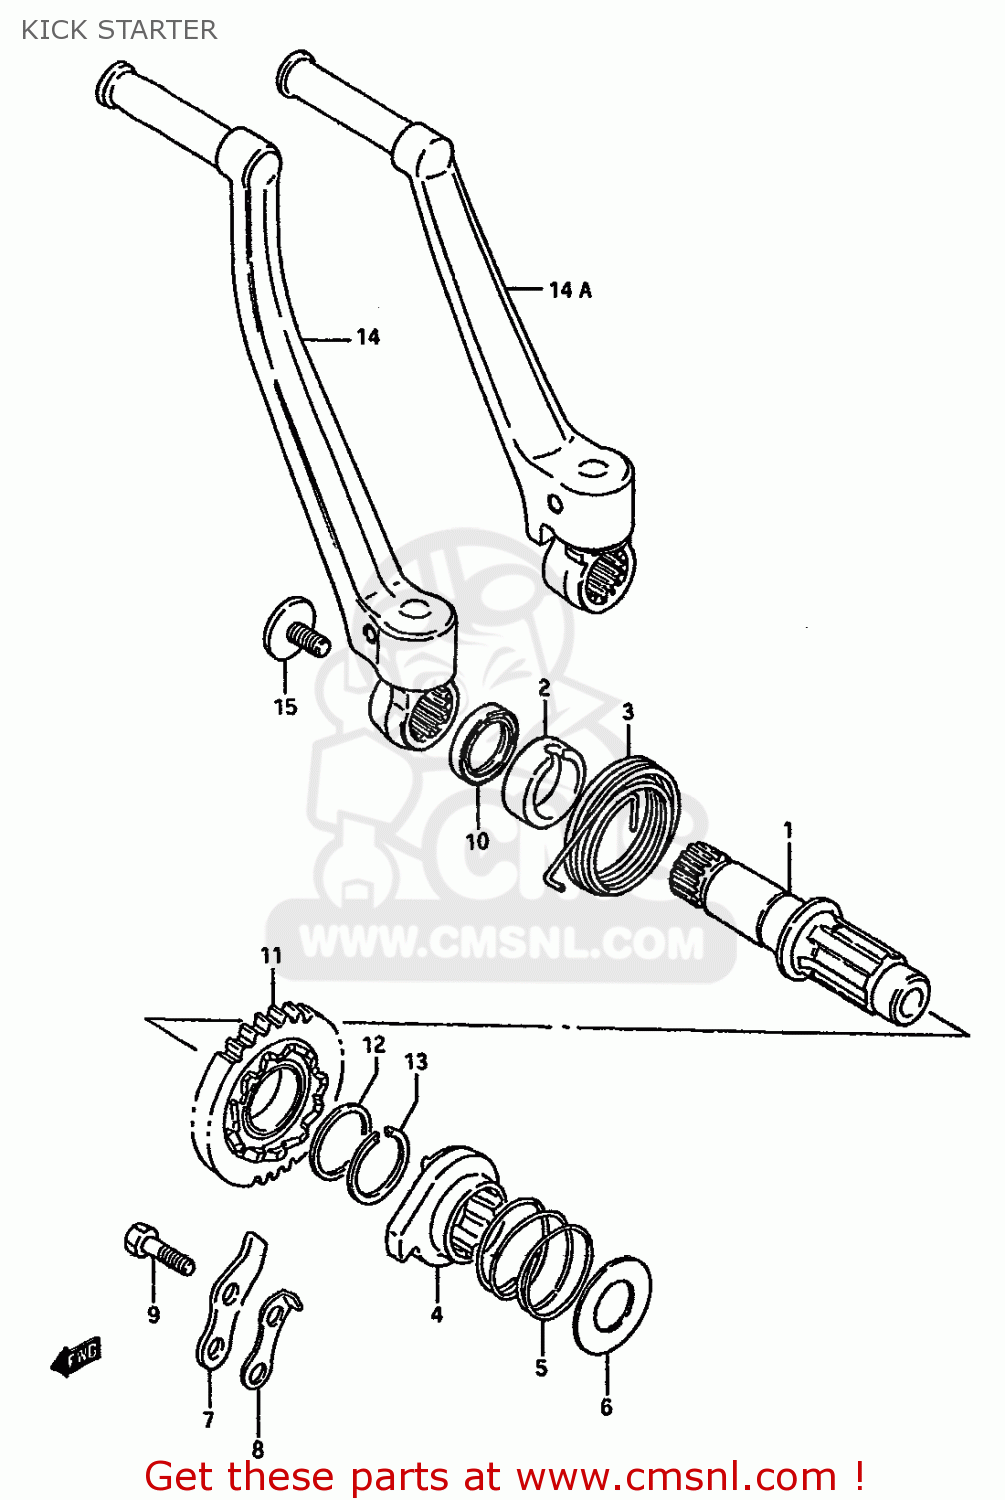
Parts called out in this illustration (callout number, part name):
1	SHAFT,KICK STARTER
2	GUIDE,KICK STARTER SHAFT
3	SPRING
4	STARTER,KICK
5	SPRING
6	WASHER
7	GUIDE,KICK STARTER
8	STOPPER,KICK STARTER
9	BOLT
10	SEAL,OIL(20X27X5)
11	GEAR,KICK STARTER DRIVE
12	SHIM
13	CIRCLIP
14	LEVER ASSEMBLY,KICK STARTER
14A	LEVER ASSEMBLY,KICK STARTER
15	BOLT
